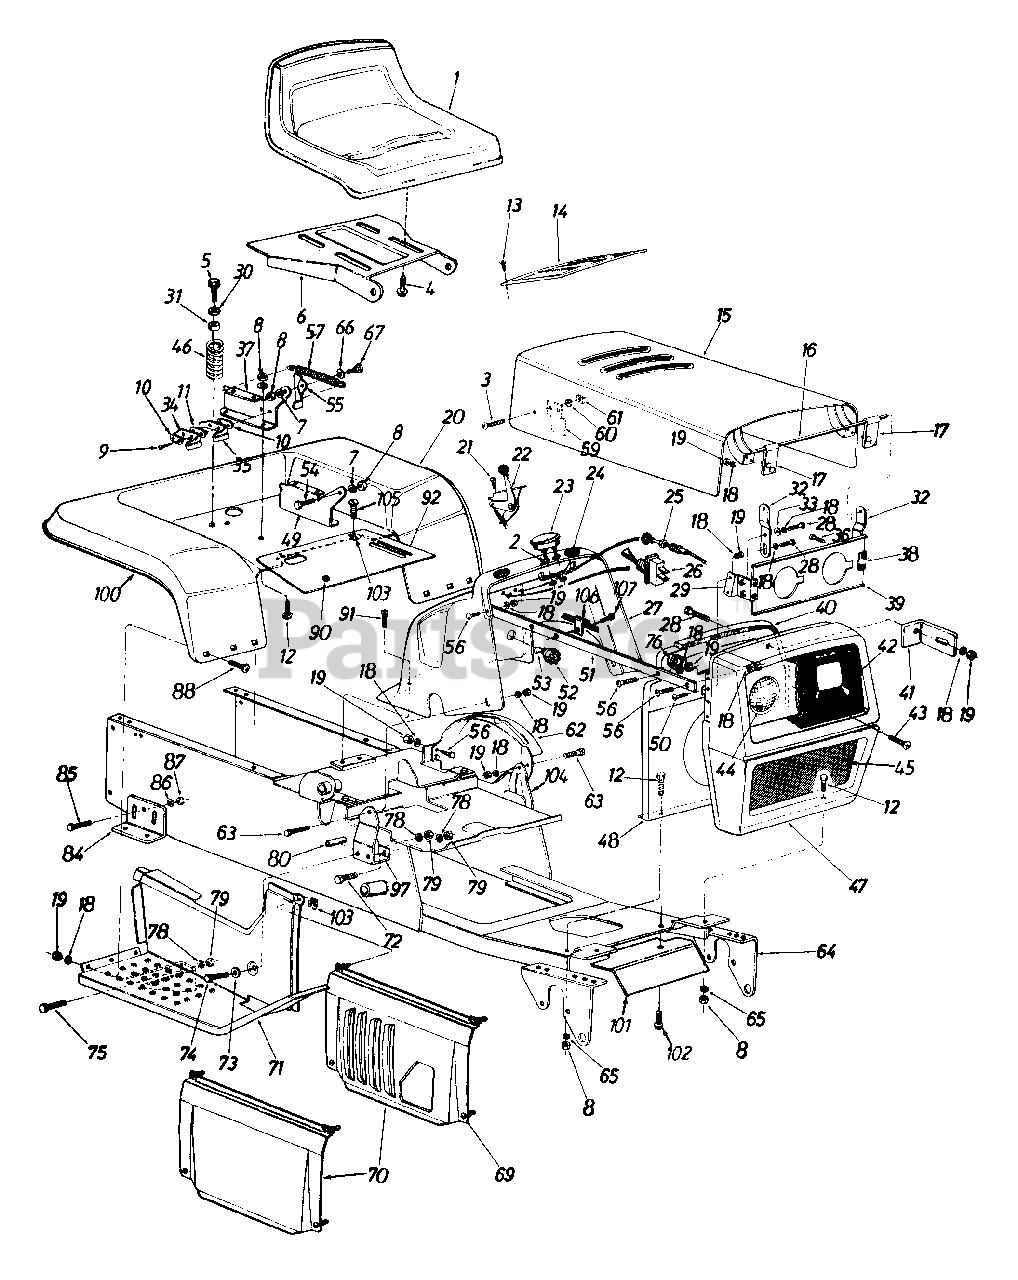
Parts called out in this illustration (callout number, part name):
1	Seat Ass'y.
2	L-Wash. .190" I.D.
3	Truss Hd. Mach. Scr. #10-24 x .38" Lg.
4	Hex Wash. Hd. Self-Tap Scr. 3/8-16 x .75" Lg.
5	Hex Wash. Hd. Tap Scr. 5/16-18 x .75" Lg.
7	L-Wash. 5/16" I.D.
8	Hex Nut 5/16-18 Thd.
9	Hex Wash. Hd. AB-Tap Scr. #8 x .5" Lg.
10	Insulator Plate
11	Insulator Boss Plate
12	Hex Bolt 5/16-18 x .75" Lg.
13	Self-Tap Oval Hd. Scr. 1/2" Lg.
14	Dash Panel Cover
17	Hood Hinge Ass'y.
18	L-Wash. 1/4" I.D.
19	Hex Nut 1/4-20 Thd.
20	Rear Fender
22	Throttle Control
23	Ammeter
24	Rubber Bumper
25	Choke Control
26	Light Switch
27	Dash Panel
28	Hex Bolt 1/4-20 x .62" Lg.
29	Hood Support Brkt. Ass'y. - R.H.
30	Fl-Wash. .344" I.D. x .875"
31	Bushing
34	Safety Switch (Seat)
35	Safety Switch (Seat)
36	Hex Bolt 1/4-20 x .38" Lg.
37	Seat Pivot Support Brkt. - R.H.
38	Hood Support Brkt. Ass'y. - L.H.
41	Heat Shield Brkt.
42	Head Lamp Bezel
43	Truss Mach. Scr. #10-24 x .50" Lg.
44	Head Lamp
45	Grille Screen
46	Compression Spring 4.5" Lg.
50	Truss Mach. Scr. 1/4-20 x .75" Lg.
51	Grille Strap
52	Ignition Switch
53	Ignition Key
54	Shld. Bolt .437" Dia. x .162"
55	Seat Lift Bracket
56	Hex Bolt 1/4-20 x .75" Lg.
57	Extension Spring 5.31" Lg.
59	Hood Spring
60	L-Wash. #10
61	Hex Nut #10-24 Thd.
62	Speed Control Guide
63	Truss Mach. Scr. 1/4-20 x .75" Lg.
66	Spr. Wash. .445" I.D. x .75"
67	Shld. Bolt .437" Dia. x .268"
69	Truss Mach. Scr. #10-24 x .5" Lg.
73	Fl-Wash. .385" I.D. x .62" O.D.
74	Hex Bolt 3/8-16 x 3.00" Lg.
75	Hex Bolt 3/8-16 x 1.00" Lg. Grade 5
76	Snap Bushing
78	L-Wash. 3/8" I.D.
79	Hex Nut 3/8-16 Thd.
80	Spacer .375" I.D. x .62" O.D. x 2.00" Lg.
84	Transaxle Support Brkt.
85	Rd. Hd. Rib Neck Scr. 3/8-24
86	L-Wash. 3/8" I.D.
87	Hex Nut 3/8-24 Thd. (Gr. 5)
88	Carr. Bolt 1/4-20 x .50" Lg.
90	Snap Bushing
91	Hex Wash. Hd. Tap Scr. 1/4-20 x .5" Lg.
103	Speed Nut #10-24 Thd.
104	Dash Panel Mtg. Brkt. - L.H.
105	Truss Mach. Scr. #10-24 x .5" Lg.
106	Clamp
107	Self-Tap Scr. 5/16 x .5" Lg.
